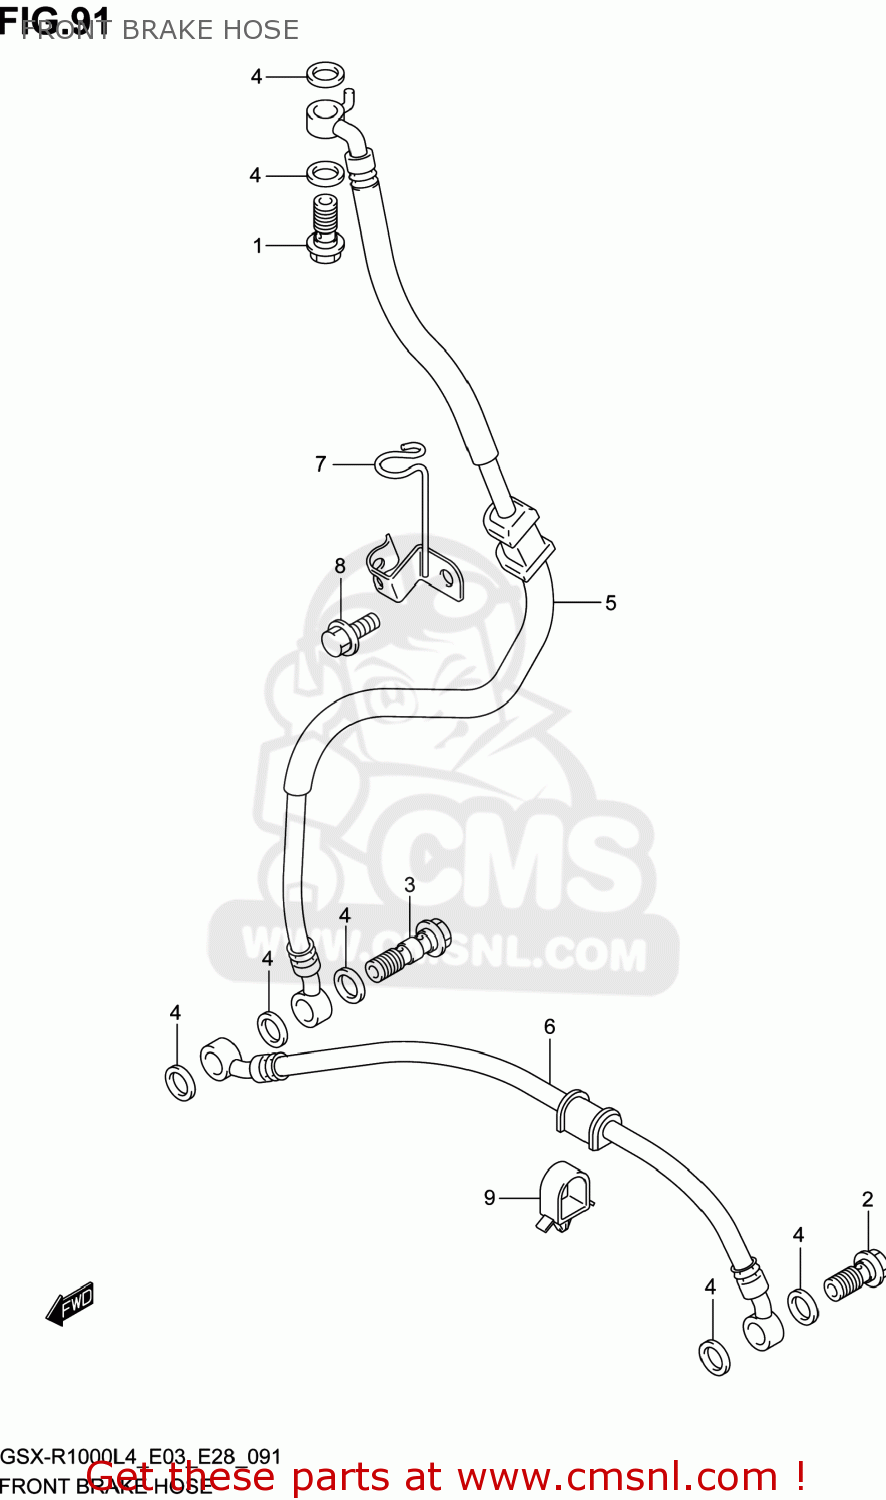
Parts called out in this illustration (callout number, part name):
1	BOLT UNION
2	BOLT UNION
3	BOLT UNION
4	WASHER(10X15X1.5)
5	HOSE,FR BRAKE NO.1
6	HOSE,FR BRAKE NO.2
7	CLAMP,FR BRAKE HOSE NO.1
8	BOLT
9	CLAMP
